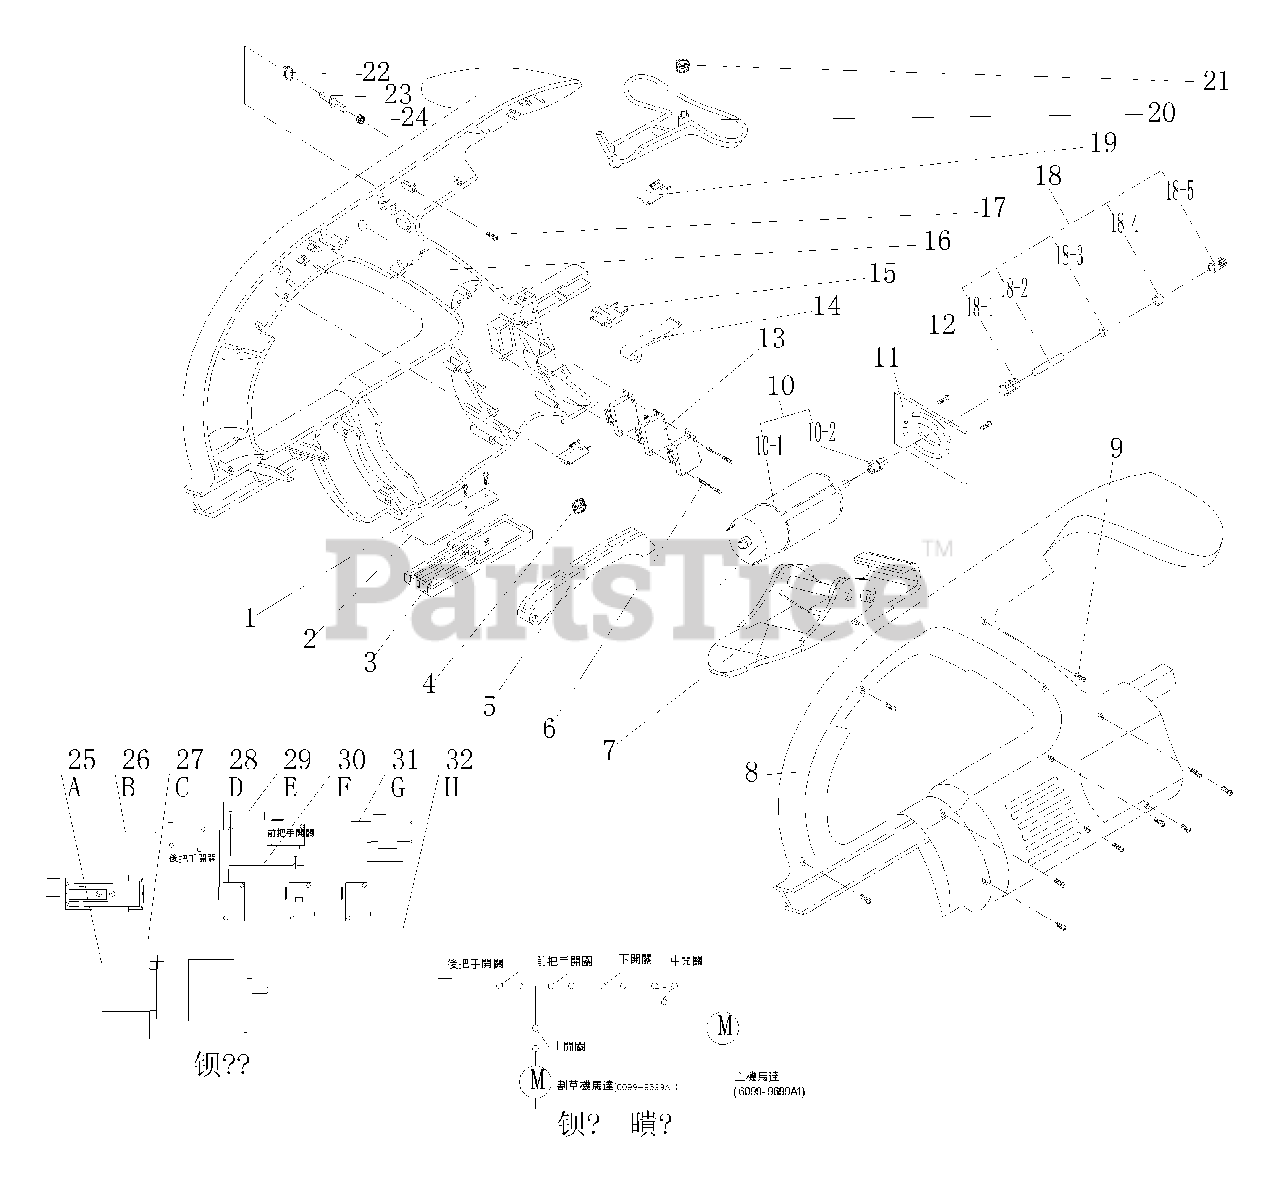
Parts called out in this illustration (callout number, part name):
2	PRESSURE PLATE
3	SOCKET, MAIN BODY
5	BUTTON, AFTER
8	HOUSING (L)
10	MOTOR ASS'Y
11	MOTOR PLATE
15	TERMINAL HOLDER
16	HOUSING (R)
18	SHAFT ASS'Y
20	BUTTON, FRONT
22	SPRING CAP
